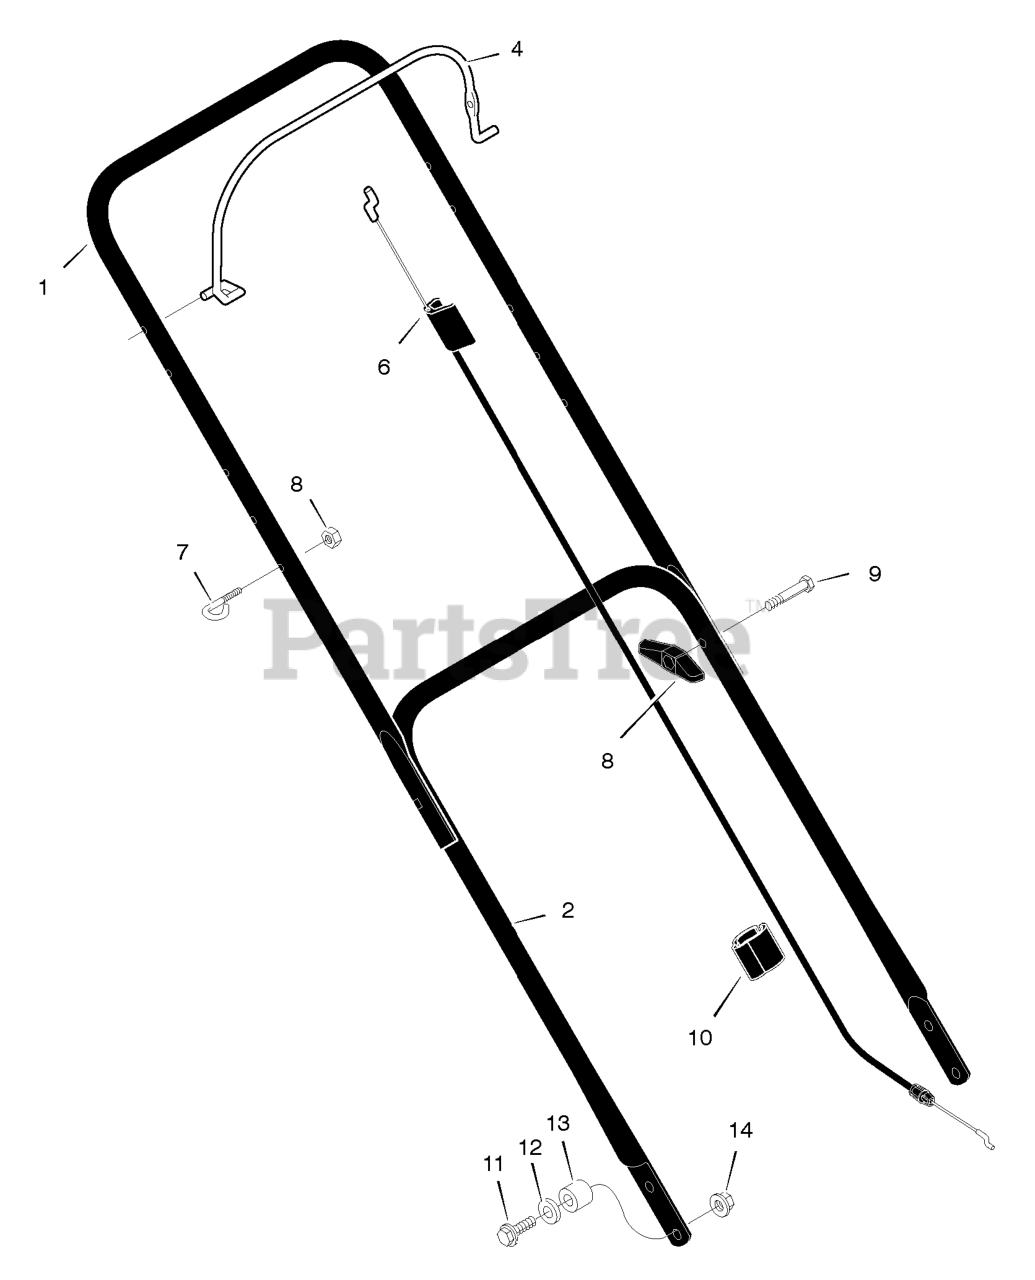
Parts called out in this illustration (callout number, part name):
1	Handle, Upper (Gray)
2	Handle, Lower (Gray)
4	Lever, Stop
6	Engine Stop Cable
7	GUIDE, ROPE
8	Locknut
10	Clip, Cable
11	Bolt
12	Washer
14	Nut
